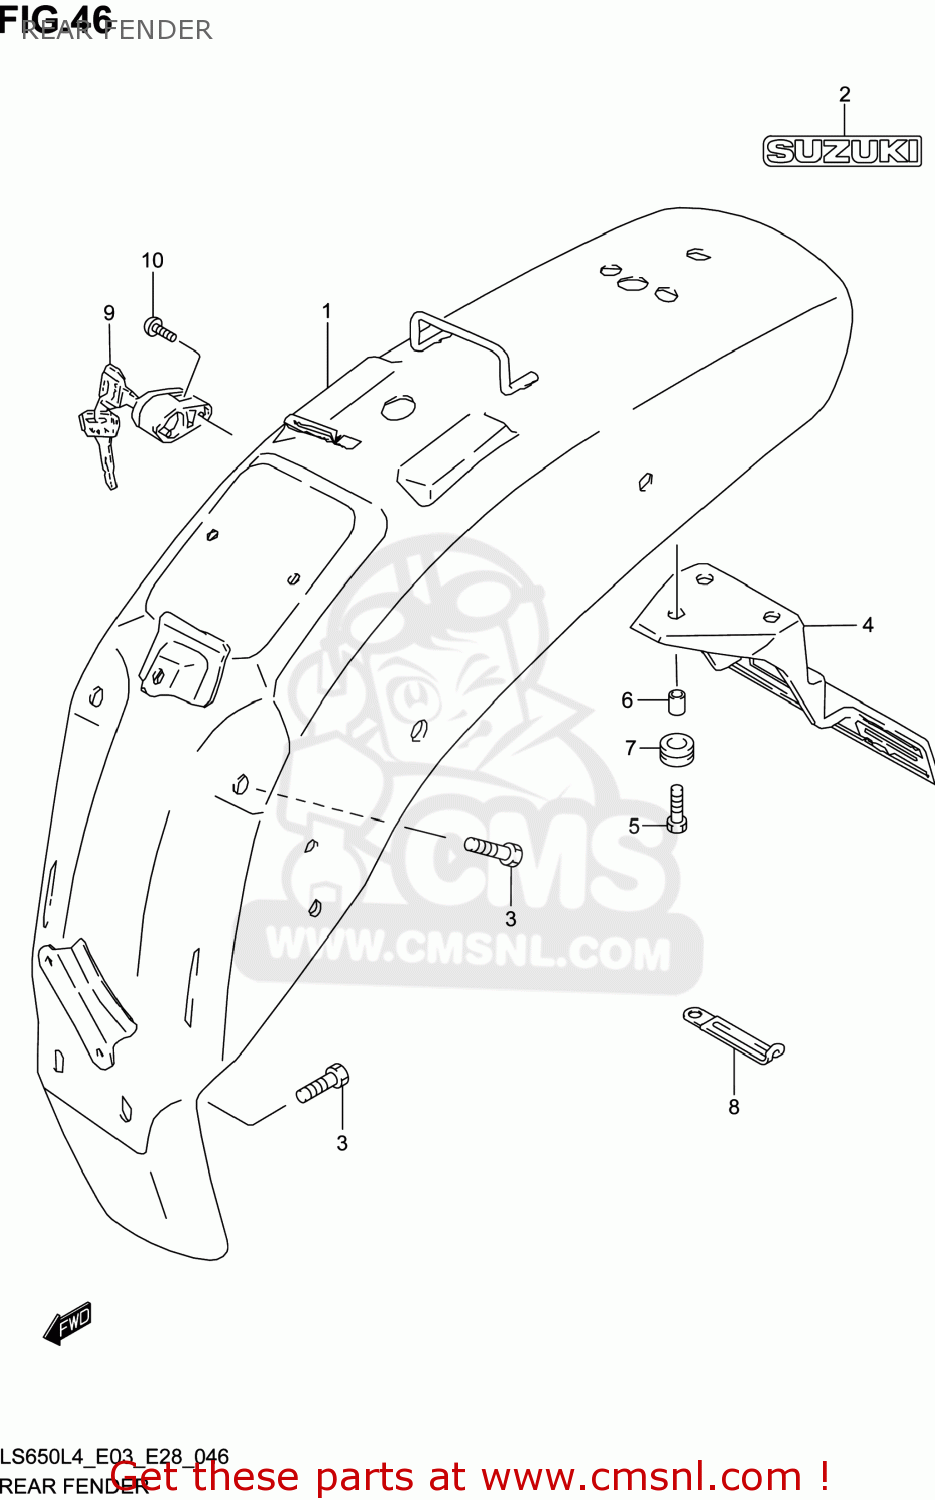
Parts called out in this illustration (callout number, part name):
1	FENDER ASSY,RR
2	EMBLEM,SUZUKI
3	BOLT(8X25)
4	BRACKET,LICENSE PLATE
5	BOLT(6X20)
6	SPACER(6.5X9X9)
7	CUSHION
8	CLAMP(L:45)
9	LOCK SET,HELMET
10	SCREW
